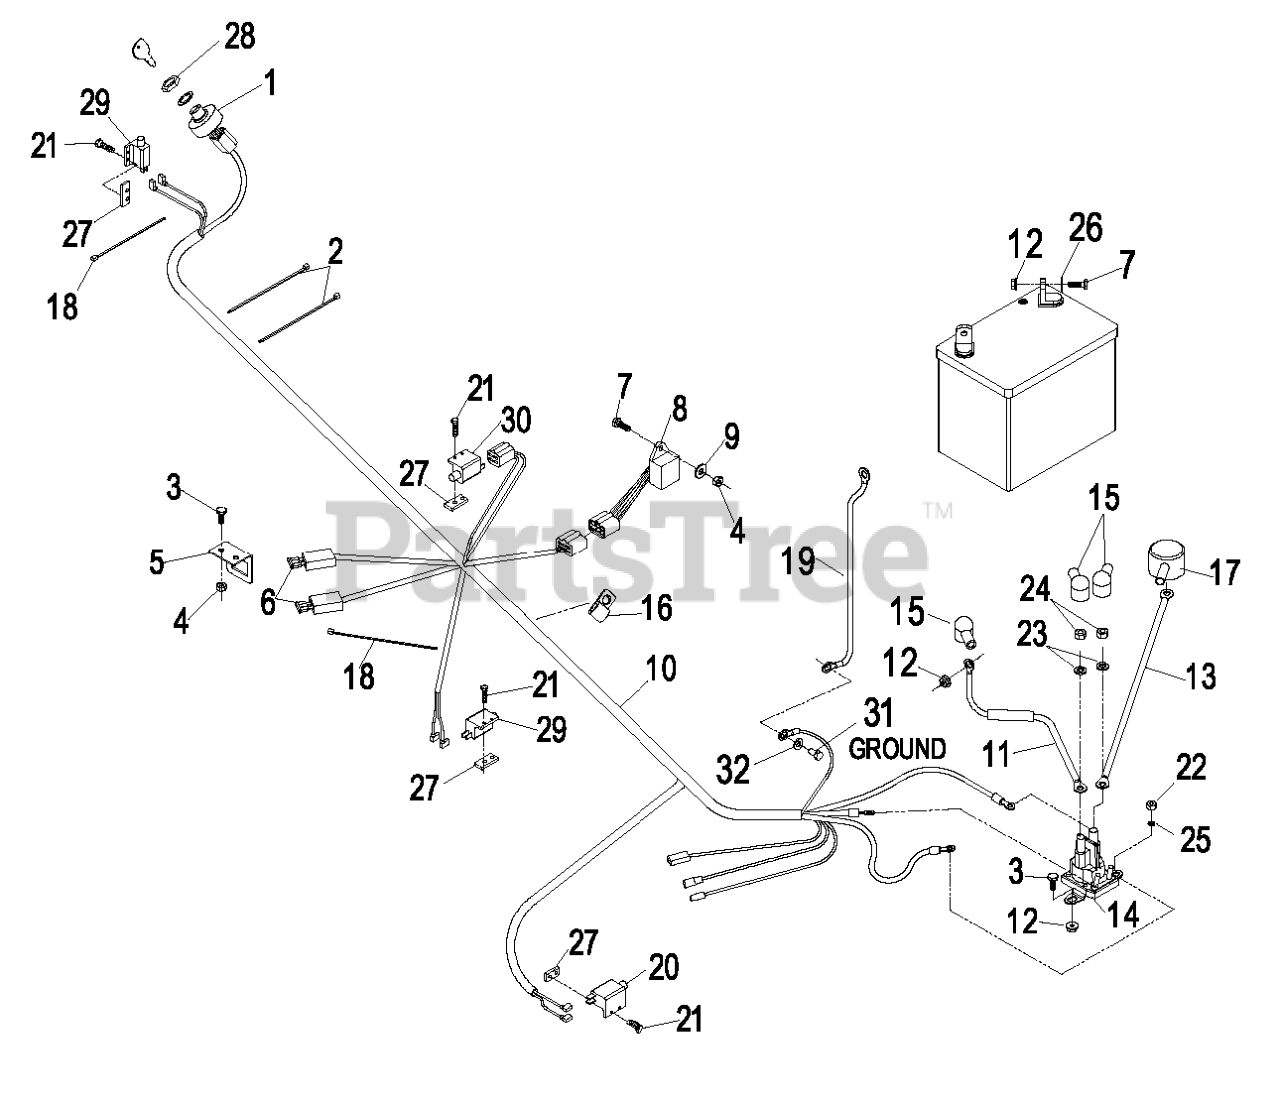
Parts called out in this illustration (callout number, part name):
1	SWITCH,IGNITION
2	TIE-PLASTIC
3	SCREW-HH
4	NUT-LOCK, NI
5	BRACKET,FUSE
6	FUSE-BLADE TYPE, 20 AMP
7	SCREW-HH
8	MODULE-OPC NO TIME DELAY
9	WASHER-FLAT
10	HARNESS,WIRING ELEC ST
11	Cable, Solenoid/Starter +
13	ASM,POSITIVE BATTERY CABL
14	SOLENOID
15	INSULATOR-SOLENOID
16	CLIP-LOOM
17	INSULATOR-BATTERY
18	TIE-CABLE
19	CABLE-BATTERY, NEGATIVE
20	SWITCH-CLOSED, NORMALLY
21	SCREW-PPH
22	NUT-HEX
23	WASHER-LOCK
24	NUT-JAM
25	WASHER-LOCK
26	WASHER-FLAT
27	PLATE-TAPPED
28	NUT-SWITCH, IGNITION
29	SWITCH-OPEN, NORMALLY
31	SCREW-HH
32	WASHER-PLAIN
